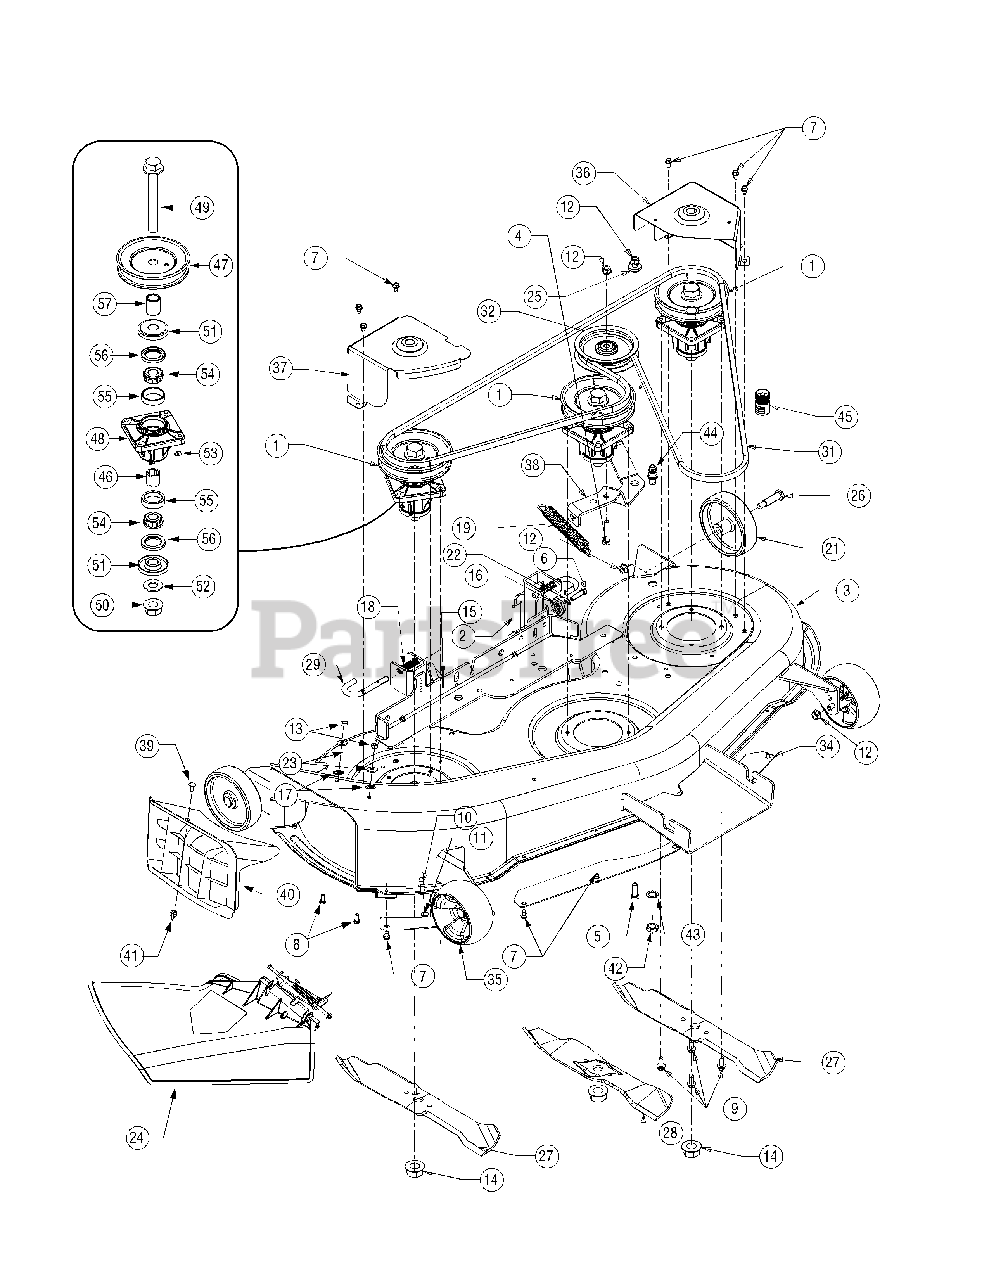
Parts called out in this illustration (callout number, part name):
1	Spindle Assembly
4	Screw, 3/8-16, 1.75
5	Hex Cap Screw, 3/8-16, 1.00, Gr5, Std
6	Screw, 5/16-18, 1.25, Gr5
7	Screw, Hx. Wash. Hd. Tapp, 1/4-20, 0.5
8	Screw, Hex Cap, 1/4-20, .750, Gr5
9	Self-tapping Screw, 5/16-18 x .75
10	Pin, Grasscatcher
11	Nut, Nylon Lock, 1/4-20
12	HEX LOCK NUT
14	Nut, Hx. Flange, 3/4-16
15	Cotter Pin, 1.0
16	Deck Adjustment Gear
18	Compression Spring, 1.75
19	Extension Spring, 7.33
20	Deck Wheel, 5.0
21	PLASTIC WHEEL 5X1.38
22	Washer, Lock, 5/16, Regular Duty
23	SPRING WASHER BELL
24	Chute Assembly, Side Discharge
25	Spacer, Shoulder, 1.00 x .38 x .38
26	Shoulder Screw
27	Blade, 16.28
28	Blade, 14.88
29	Rod, Handle, Deck Release .375 Dia
31	Belt, V-Type
32	Idler Pulley, 4.25
39	Carriage Screw, 1/4-20, .62
40	Mulch Plug
41	WING NUT 1/4-20
42	Nut, Hex, M16-1.5
43	Washer, Lock
44	Port, Water
45	Coupler, Hose
46	Spacer, Bearing, .780 x 10 x 1.0425
47	Pulley, 6.3 Dia.
48	Housing, Spindle (order assembly)
49	Bolt, Spindle, 3/4-16, 5.85
50	Nut, Flange Lock, 3/4-16
51	Spacer, Spindle
52	Washer, Flat, .760 x 1.5 x .120
53	GREASE FITTING
54	Cone Bearing, Tapered Roller, .750
55	Cone Cup, Tapered Roller, .750
56	Seal, Oil
57	Spacer, 1.322
58	Spacer, Bearing, .780 x 10 x 1.0425
59	Pulley, 6.3 Dia.
